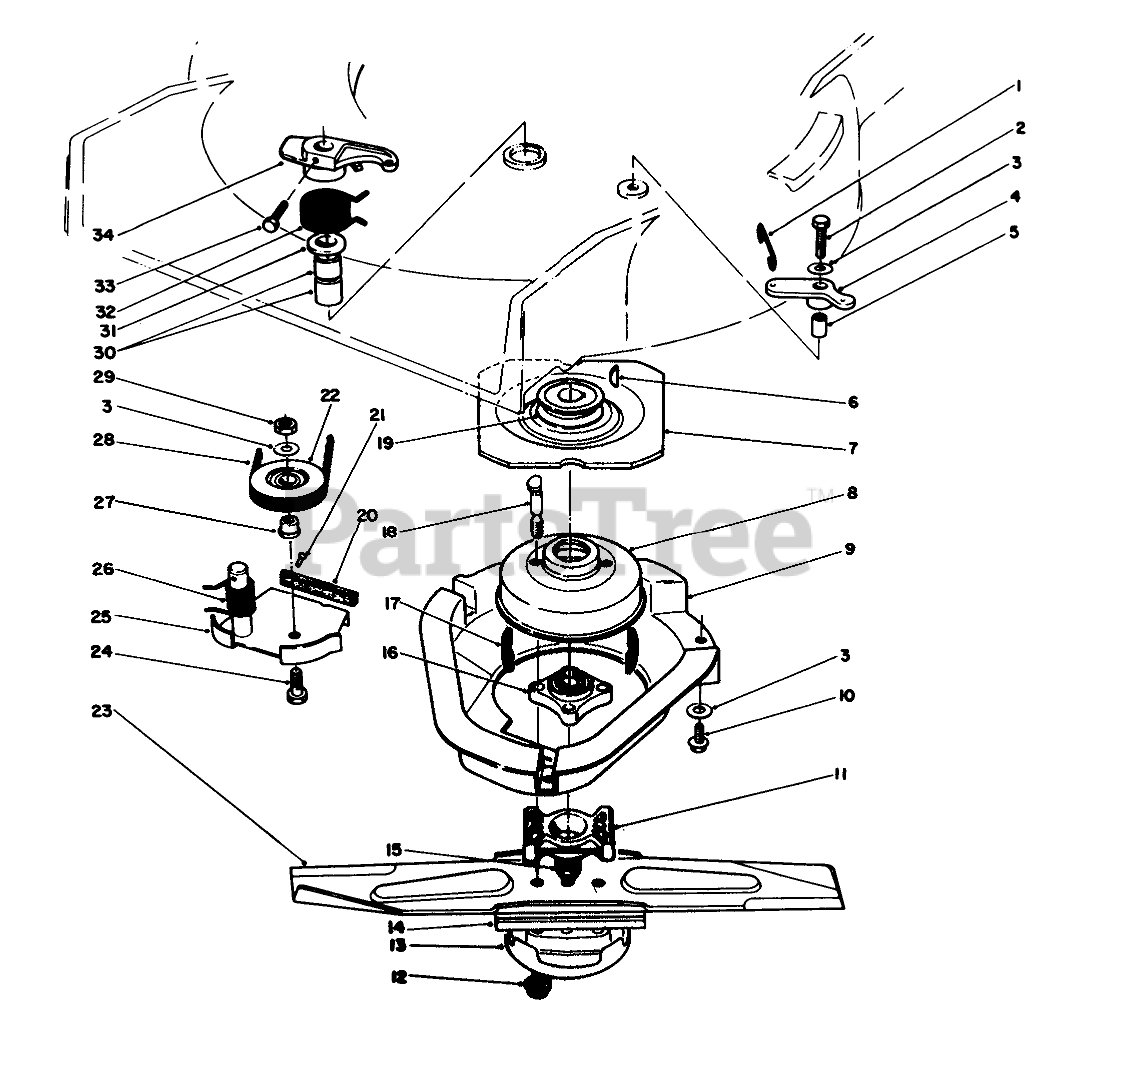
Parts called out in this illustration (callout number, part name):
1	LINK-CONTROL
2	SCREW-HH
3	WASHER-PLAIN
4	BELLCRANK
5	SLEEVE-BELLCRANK
6	KEY-WOODRUFF
7	Flywheel
8	Drum-Brake
9	SHIELD BBC
10	SCREW-HWHTF
11	SPACER-BLADE
12	NUT-LOCK
13	CUP-SCALP, ANTI
14	Stiffener
15	NUT-LOCK, NI
16	HUB ASM
17	DAMPENER-VIBRATION
18	BOLT-BLADE
19	PULLEY
20	Pad-Brake
21	.185 DIA X .375 RT +
22	PULLEY-IDLER
23	Blade-21" (Incl. Ref. #14)
24	SCREW-HH
25	Brake Plate (Incl. Ref. #20 & 21)
26	SPRING-TORSION
27	HUB-PULLEY, IDLER
28	V-BELT
29	NUT-LOCK, NI
30	BEARING
31	WASHER
32	SPRING-TORSION
33	SCREW-HH
34	LEVER
